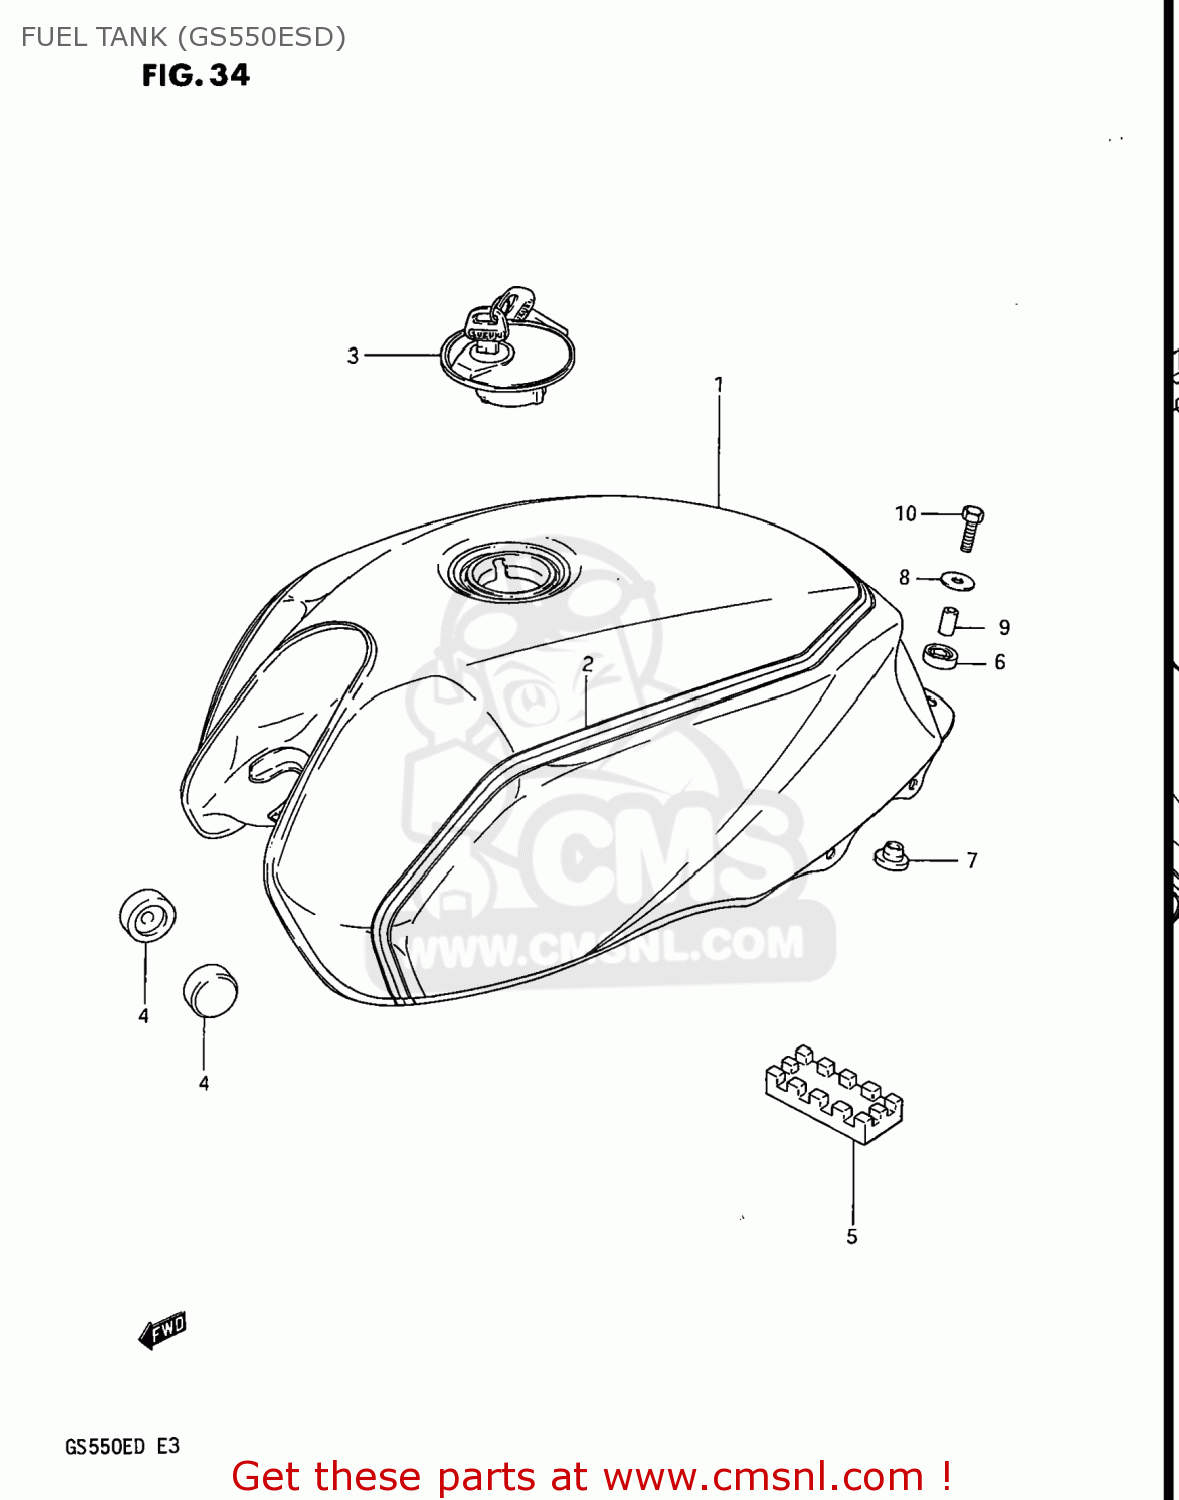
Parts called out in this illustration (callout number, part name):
1	TANK ASSEMBLY,FUEL
2	TAPE SET,FUEL TANK
3	CAP ASSEMBLY,FUEL TANK
4	CUSHION
5	CUSHION,FUEL TANK
6	CUSHION
7	CUSHION
8	WASHER (6.5X24X1.6)
9	SPACER
10	BOLT
